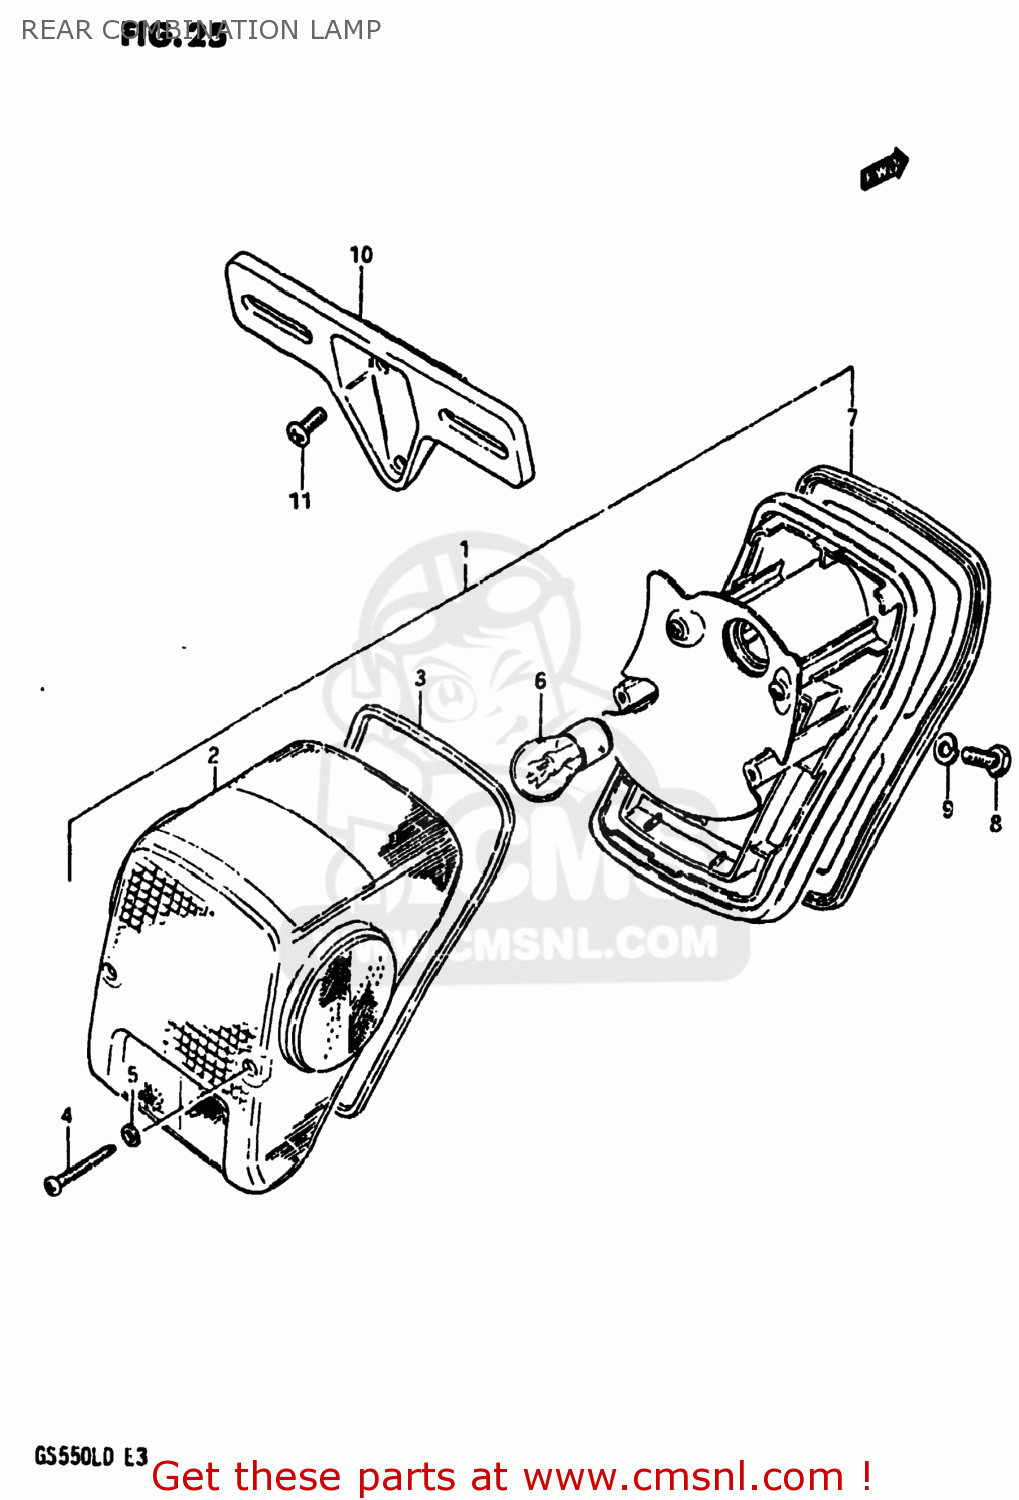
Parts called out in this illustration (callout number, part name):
1	LAMP ASSEMBLY,REAR COMBINATION
2	LENS
3	GASKET (NAS)
4	SCREW
5	GASKET (NAS)
6	BULB(12V23/8W,TOKAI DENSO)
7	CUSHION,REAR COMBINATION LAMP
8	BOLT
9	LOCK WASHER
10	BRACKET,LICENSE PLATE
11	SCREW
